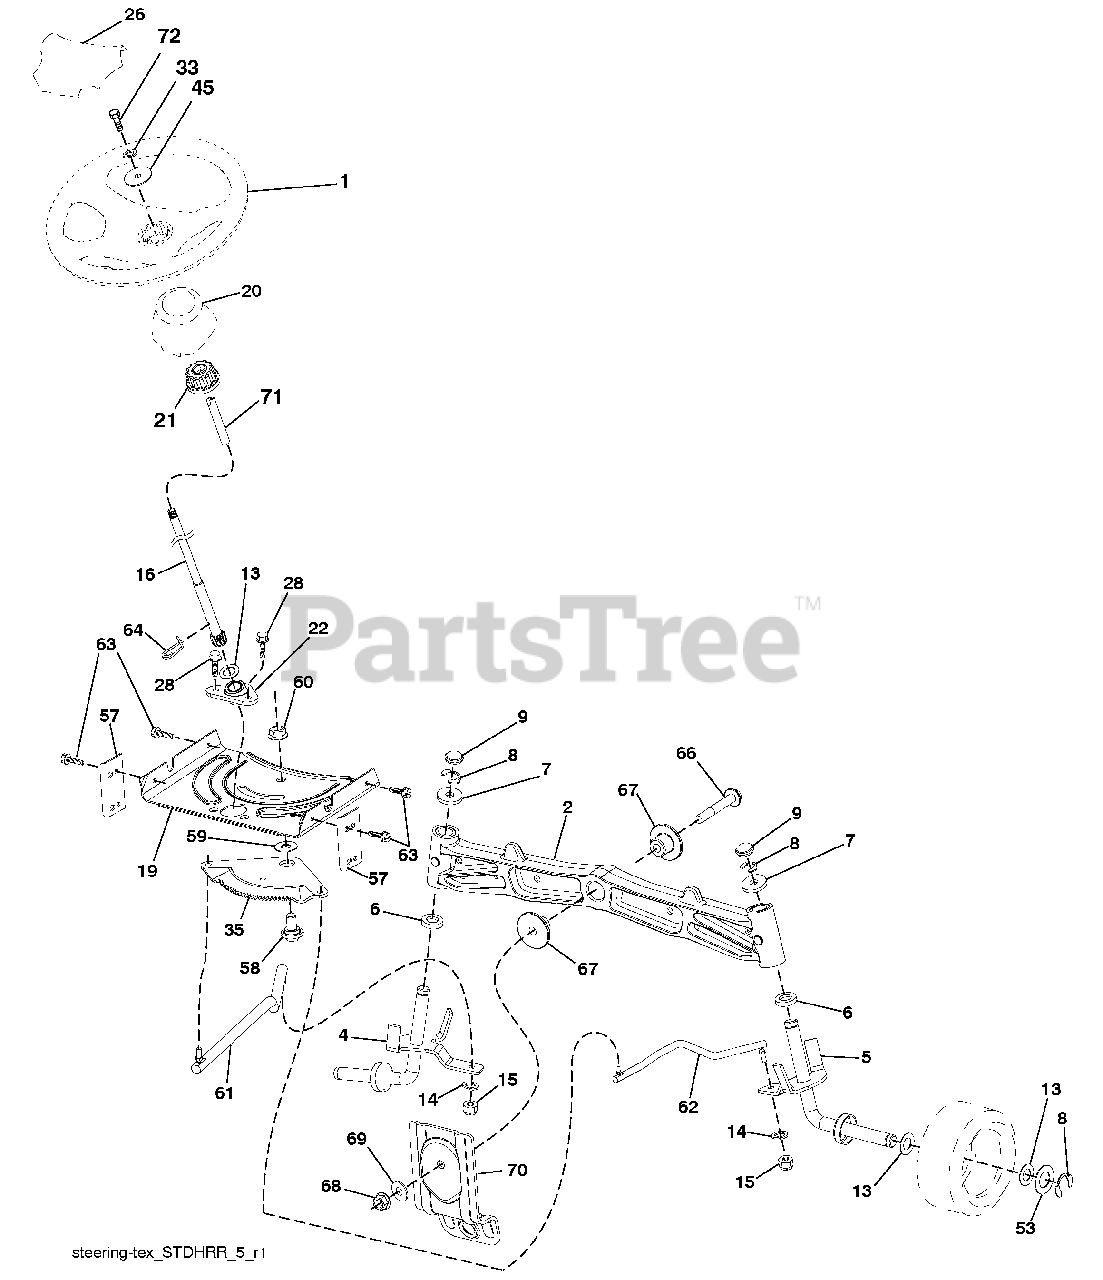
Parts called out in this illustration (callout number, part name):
1	Wheel, Steering
2	Axle Asm., Front
4	Spindle Asm., LH
5	Spindle Asm., RH
6	Washer Thrust 0.75 x 1.23
7	Washer 25/32 x 1-5/8 x 16 Ga.
8	Ring, Clip #T5304-75
9	Cap, Spindle
13	Washer 25/32 x 1-1/4 x 16 Ga.
14	Washer Lock 3/8
15	Nut, Crown Lock 3/8-24 unf
16	Shaft Steering
19	Plate Steering
20	Boot, Steering
21	Adapter, Wheel Steering
22	Strg. Supt. Lower
26	Insert, Wheel Steering
28	Screw 3/8-16 x 3/4
33	Washer Lock 5/16
35	Gear, Sector Plate
45	Washer 11/32 x 2-3/8 x 12 Ga.
53	Washer Hardened .793 x 1.637 x .060
57	Bracket Upstop
58	Bolt Shoulder Sector Pivot CFM
59	Washer Thrust Sector Steering
60	Nut Flange Lock 5/8-11
61	Draglink, LH
62	Draglink, RH
63	Screw 5/16-18 x 3/4
64	Retainer Clip Spring Steering
66	Bolt Hex Fghd 7/16-14 x 3 Serr
67	Bushing PM Front Axle
68	Nut Lock Flange 7/16-14 Gr. 5
69	Washer 1.5 x .505 x .118
70	Bracket Deck Susp. Front
71	Shaft Ext. Steering
72	Bolt 5/16-18 x 4 W/Patch
